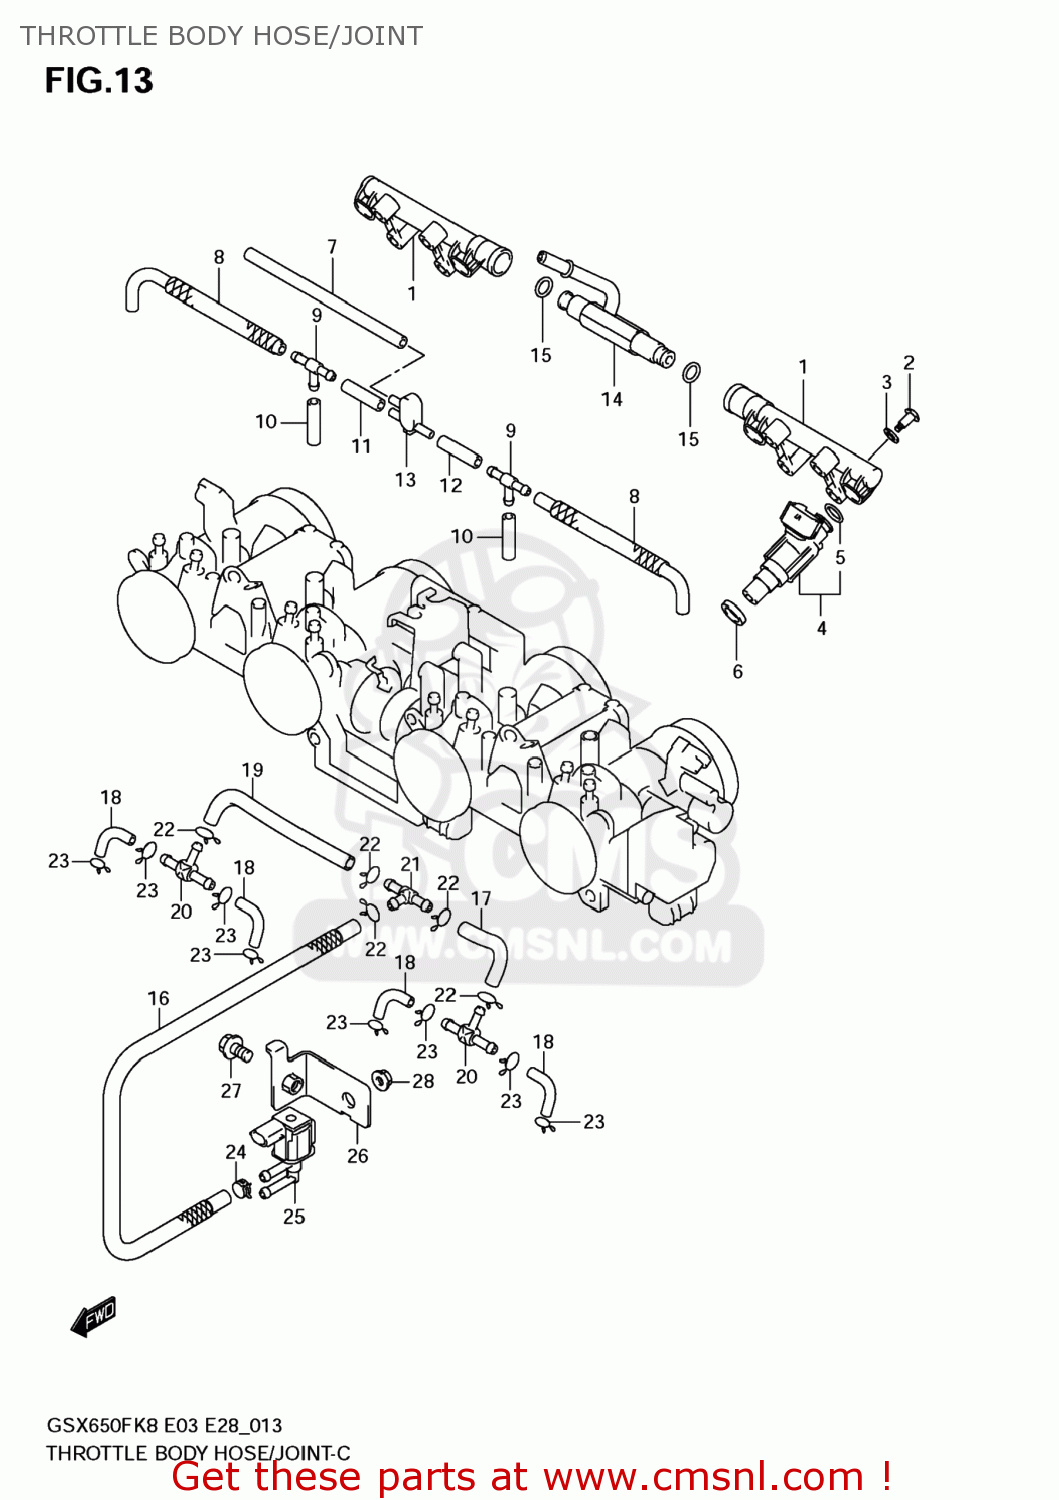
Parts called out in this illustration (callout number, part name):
1	DELIVERY PIPE
2	SCREW
3	PACKING (NAS)
4	INJECTOR ASSY
5	O RING
6	SEAL
7	HOSE
8	HOSE
9	3WAY,VACUUM HOSE
10	HOSE
11	HOSE
12	HOSE
13	JOINT
14	NIPPLE
15	O RING
16	HOSE
17	HOSE
18	HOSE
19	HOSE
20	NIPPLE
21	NIPPLE
22	CLIP
23	CLIP
24	CLIP
25	VALVE,CANISTER PURGE
26	BRACKET,SOLENOID VALVE
27	BOLT
28	NUT
